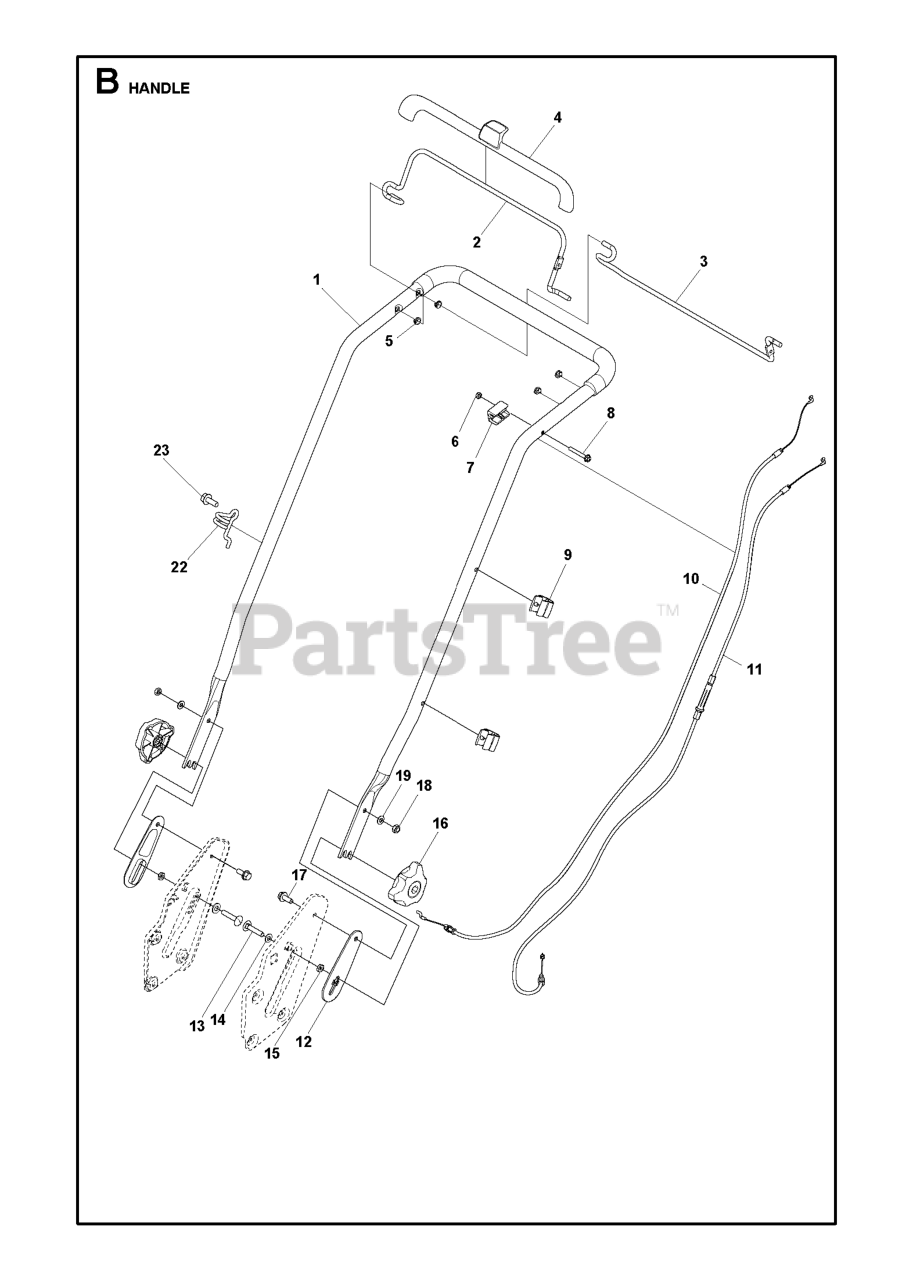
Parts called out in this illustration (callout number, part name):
6	NUT FLANGE - M6
15	NUT ML6M M8
18	LOCKNUT M8
23	SCREW
